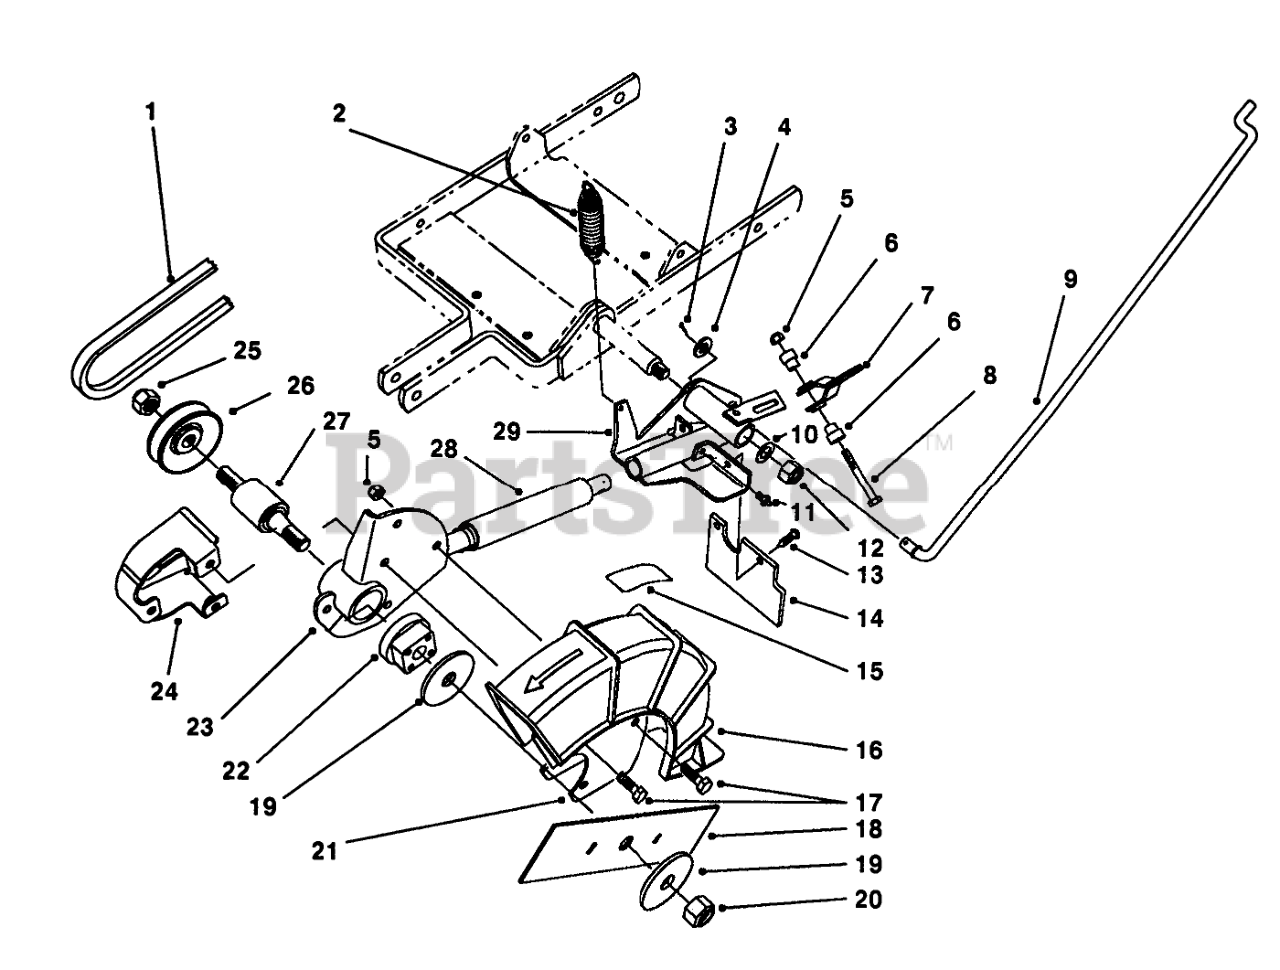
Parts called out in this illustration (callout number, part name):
1	V-BELT
2	EXT. SPRING
3	PIN-COTTER
4	WASHER-FLAT
5	NUT-LOCK, NI
6	SPACER-PIVOT LEVER
7	LEVER WA
8	SCREW-HH
9	LOWER CONTROL ROD
10	WASHER-PLAIN
11	FITTING-GREASE
12	NUT-LOCK, NI
13	PANEL FASTENER
14	RUBBER GUARD
15	Decal-Warning
16	Blade Guard Assy. (Incl. Ref. #15)
17	SCREW-HWHTF
18	9" EDGER BLADE
19	WASHER-LARGE
20	NUT-HEX
21	GUARD PLATE
22	BRG SHIELD
23	HUB ASM
24	PULLEY GUARD WA
25	NUT-LOCK, NI
26	PULLEY
27	SPINDLE ASM
28	SPRING & BELLOW ASM
29	PIVOT ARM WA
